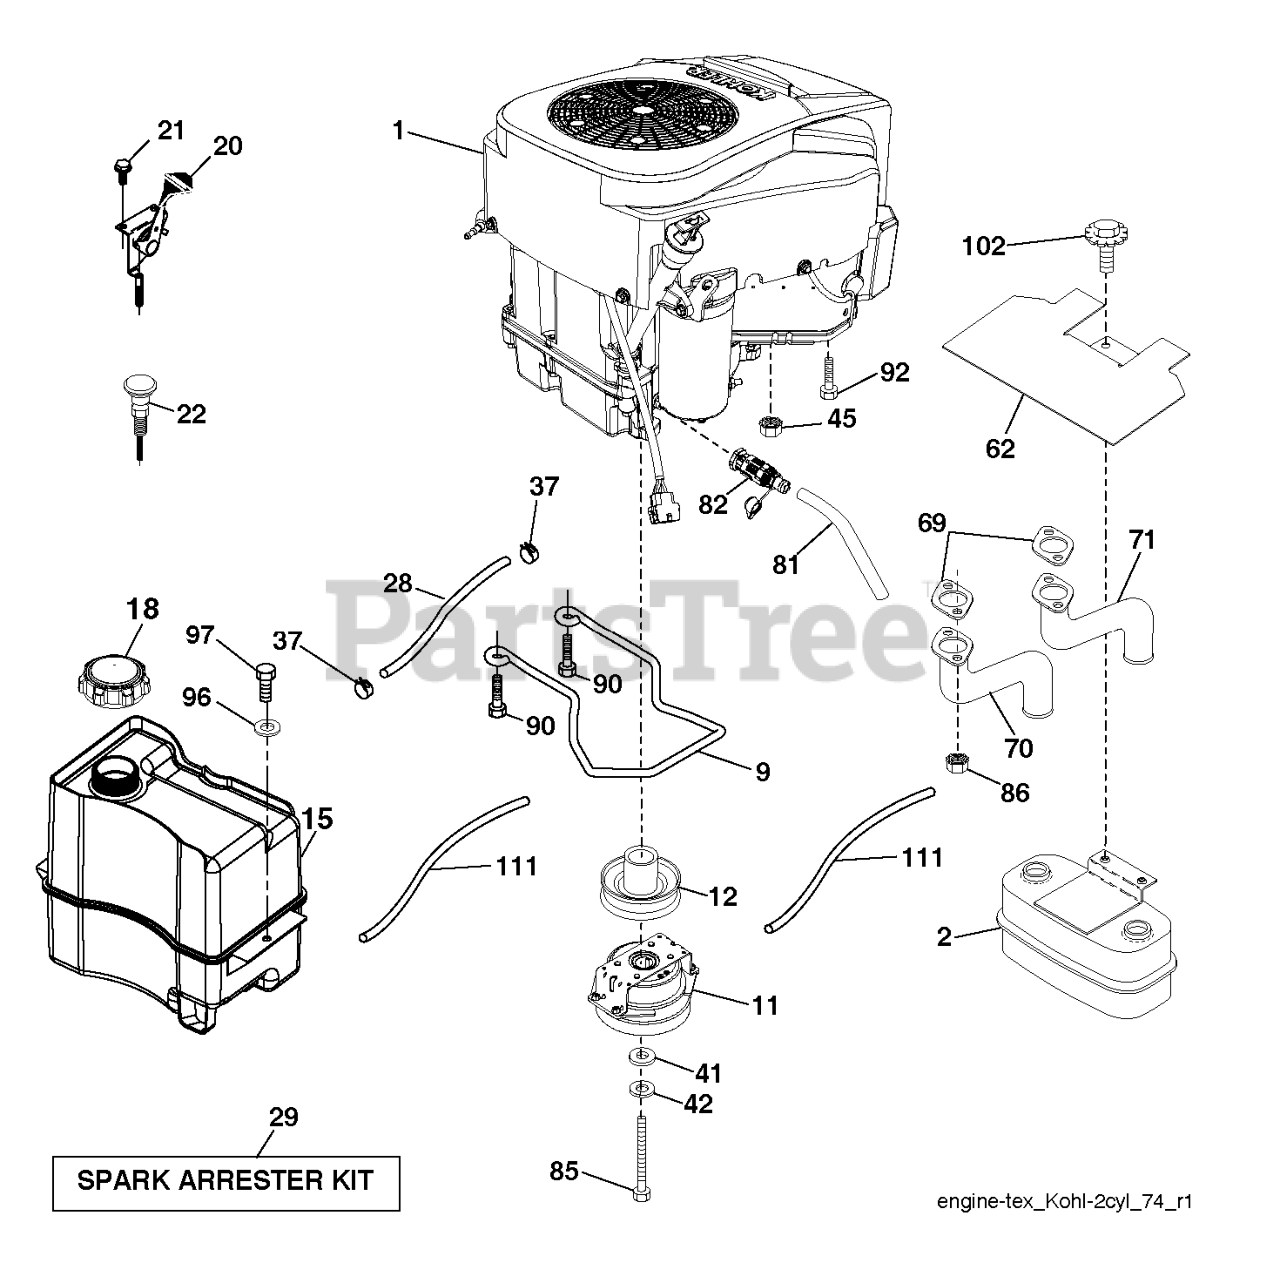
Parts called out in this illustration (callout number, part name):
2	MUFFLER.ASM.TWIN.MNTG.BRACKET
9	KEEPER.BELT.ENG.4.25"2.BLT.431
11	CLUTCH.OGURA.5.0PD.GT1.5A-EH07
12	PULLEY.ENGINE.TUFFTORQ
15	TANK.ASM.FT.2.5GAL.W/CAP.EPA17
18	FUEL.CAP.ASM.2.25TETHRED.RATCH
20	THROTTLE CONTROL
21	SCREW.#10 X 0.750.BOS
22	CONTROL.CHOKE.ERGO.PUSH-IN.BLA
28	LINE.FUEL.64"REAR.EMIS
29	KIT.SPARK ARRESTOR 794945 B&S
37	HOSE CLAMP
42	WASHER 7/16 LOCK
45	NUT
62	SHIELD.HEAT.MUFFLER
69	GASKET.EXHAUST.KOHL.CV18-CV26
70	PIPE.EXHAUST.LH.CV18/20
71	PIPE.EXHAUST.RH.CV18/20
79	SCREW.SOCKET HD.5/16-1
81	TUBE, DRAIN OIL ASM.
82	VALUE.OIL.DRAIN
85	BOLT.HEX.7/16-20X3.75.GR5.RED
90	SCREW 3/8-16X1
92	SCREW 3/8-16X1
96	WASHER
97	SCREW HEXWSHR 1/4-20X3/4
102	SCREW
111	RP PURGE LINE
